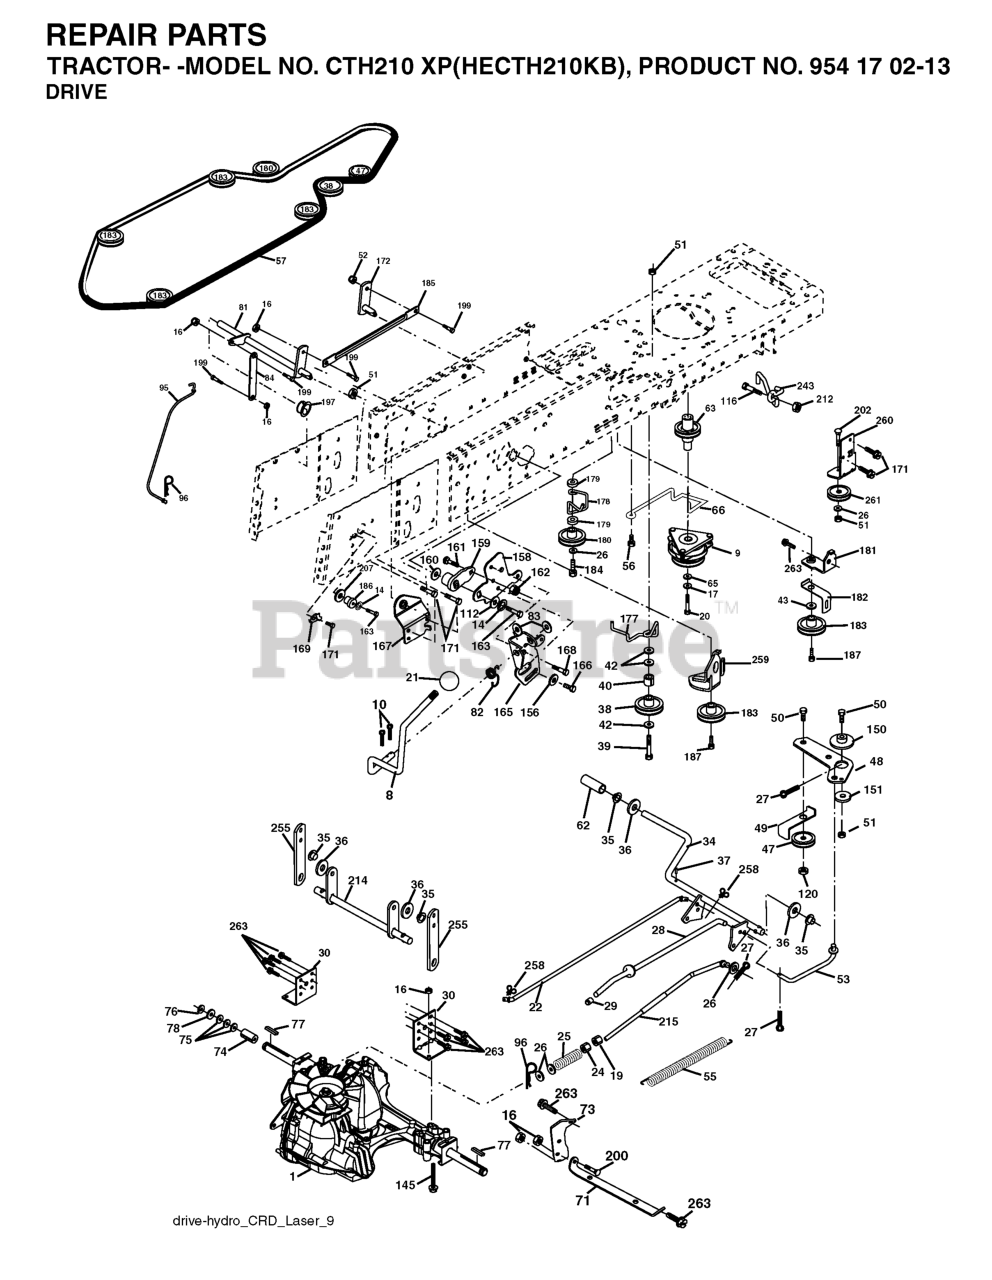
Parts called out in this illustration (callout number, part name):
8	ROD.SHIFT.FENDER.ADJ.LT.CRD
10	PIN COTTER
14	LOCKWASHER
16	NUT.71038.31-18.HEX.NYLOCK
19	NUT
20	BOLT HEX 7/16-20X4-1/4"
21	KNOB.DUCKHEAD.1/2
22	ROD
24	NUT
25	SPRING ROD LT
26	WASHER
27	COTTER PIN
28	ROD, PARKING BRAKE
29	PLUNGER CAP
30	BRKT, TRNSXLE MNT 20"
34	SHAFT, FOOT PEDAL
35	BEARING.NYLON
37	DRIVE PIN
38	PULLEY.FLAT
42	WASHER
47	IDLER PULLEY
48	BELLCRANK, CLUTCH
49	RETAIN BELT
50	BOLT.3/8-16X1.50
52	LOCKNUT
53	LINK, CLUTCH LT
55	SPRING, RETURN LT
56	SCREW.3/8-16
57	V-BELT 113"
62	COVER, PEDAL (1 2)
63	PULLEY.ENGINE.CVX.LT
65	LOCKWASHER
66	KEEPER BELT ENGINE
71	STRAP TORQUE LH HYDRO
73	STRAP TORQUE RH HYDRO
74	SPACER AXLE
77	SQUARE KEY
81	ASM.CROSS.SHAFT.REAR.CRD.0510
82	SHIFT SPRING
83	WASHER
84	LINK.PNT.TRANSAXLE.0510.CRD
95	LINK
96	RETAINER M
116	BOLT D
120	NUT LOCK FLG 3/8-16 UNC
145	BOLT HEX 5/16-18 GR 5
150	BUSHING.BELLCRANK.GRD.DR
151	WASHER 12/32X2X10GA
156	WASHER.SRRTD.5/16
158	BRACKET
159	RB HUB.SHIFT
160	Washer 29/32 x 1 - 1/4 x 16 Ga.
161	BOLT
162	NUT.CROWNLOCK.1/4
165	RP BRACKET
166	CAPSCREW.HXHD.FLG.5/16-18X.625
167	BRACKET.SUPT.SHIFT.CRD
168	BOLT.SHOULDER.5/16-18X
169	PLATE.FASTENING.CROSS.SHAFT
172	LINK
180	PULLEY.FLAT.IDLER
181	BRACKET
182	BELT GUIDE
184	SCREW.HXWSH.3/8
185	LINK
186	HUB.TAPERED.ROUND.CRD
187	BOLT.5/16-18X1.25
197	NYLINER SNAP 5/8" ID
199	BOLT SHOULDER 5/16-18 UNC
207	WASHER NYL
212	NUT
214	LEVER
215	ROD
243	BRKT ASM MTNG
255	SHAFT
258	CLIP RETAINER
259	BRACKET
261	FLAT IDLER PULLEY
263	SCREW, 3/8-16X3/4
